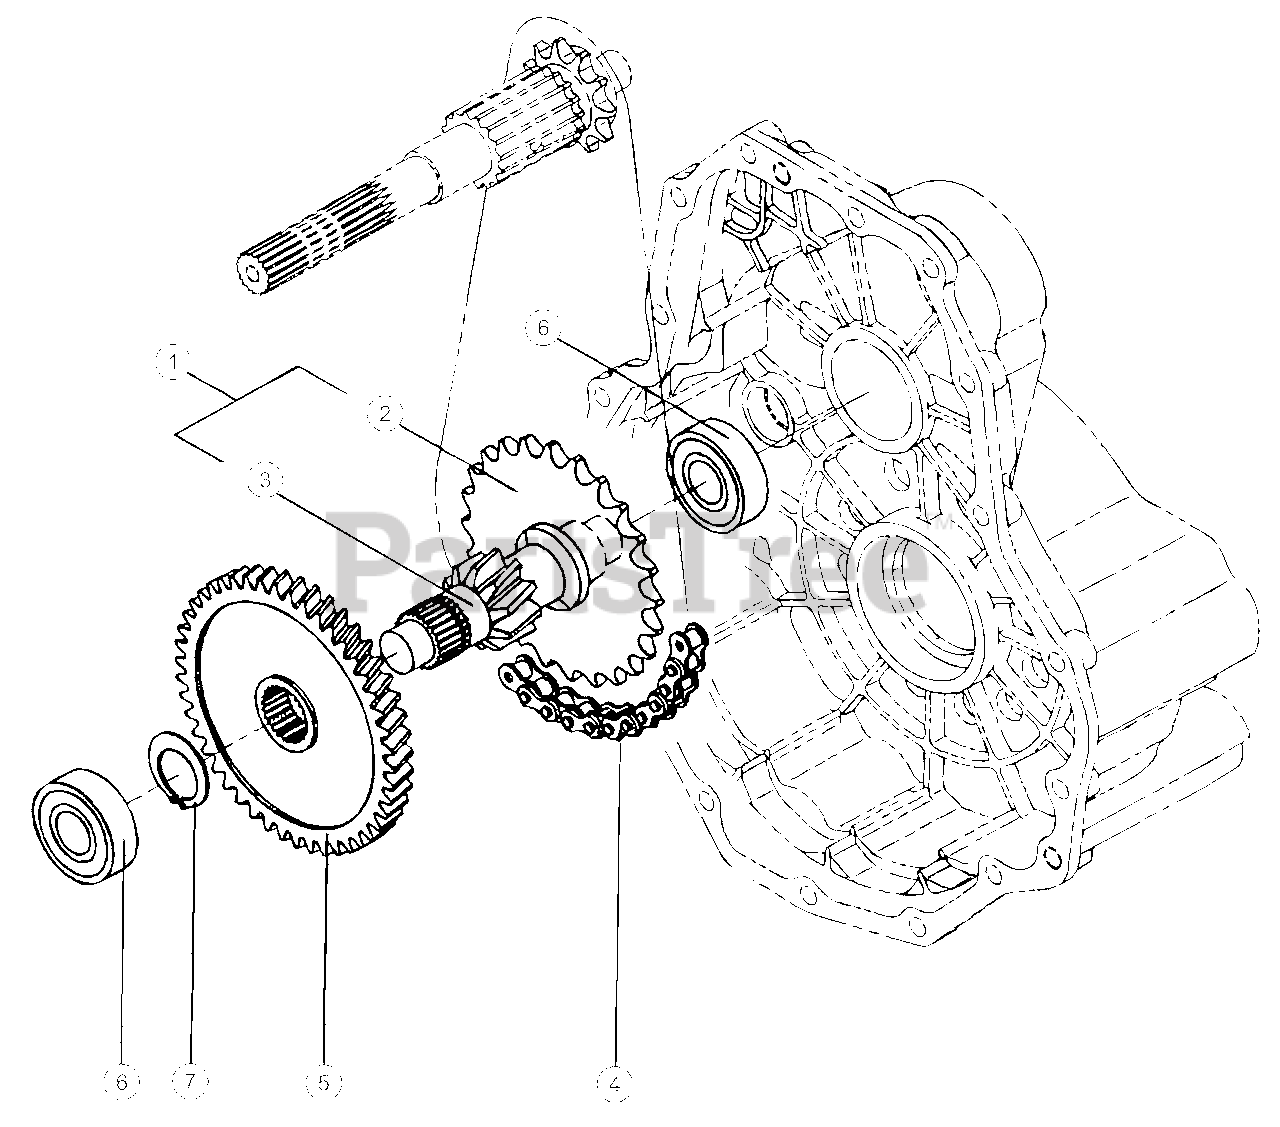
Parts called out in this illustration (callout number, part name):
1	Reduction Shaft Assembly
3	Shaft, Reduction
4	Chain, 40 x 34
5	Gear, 46H, Reduction
6	Bearing, 6204R, SH2
